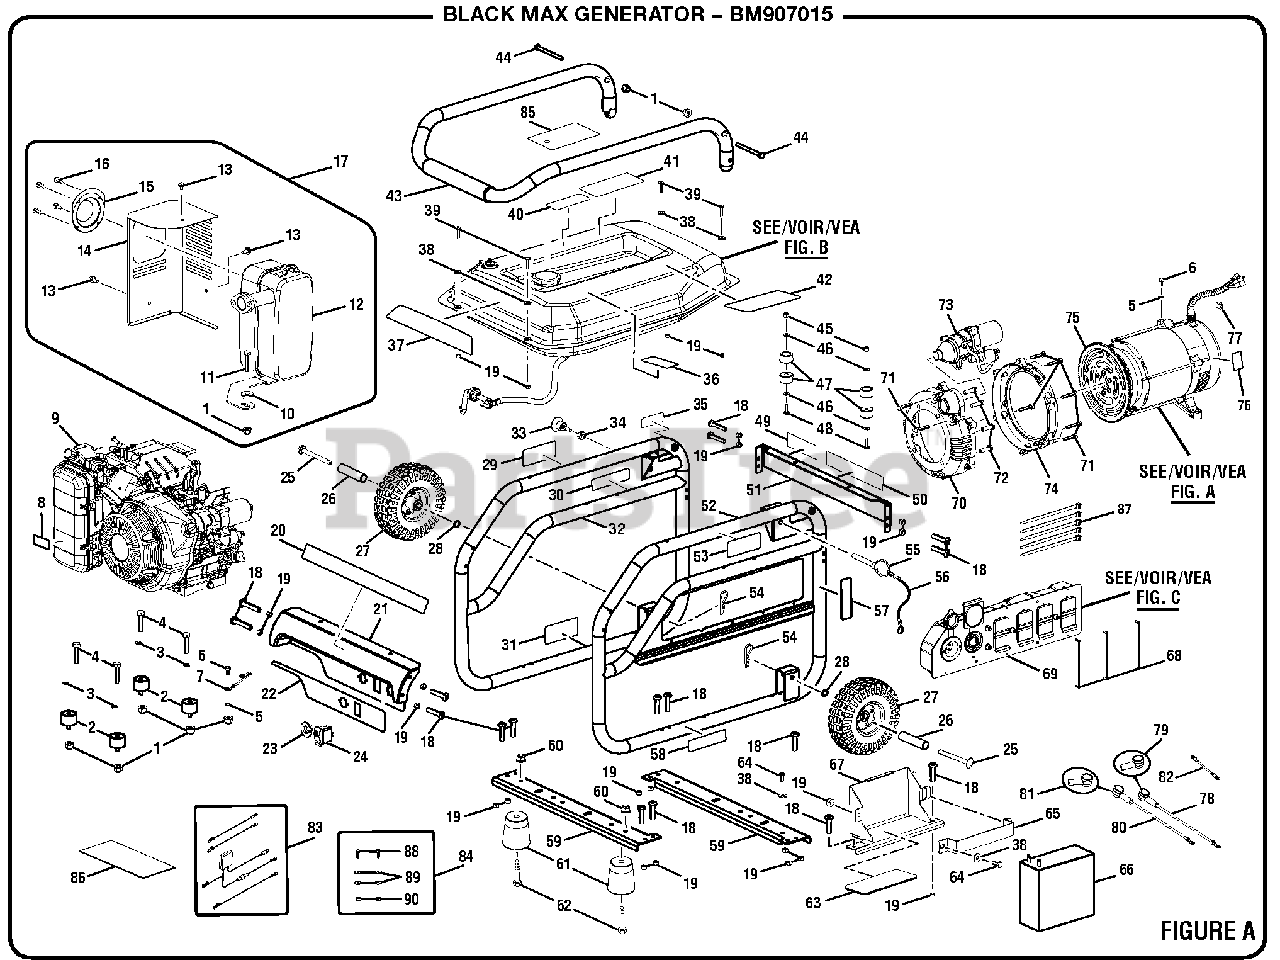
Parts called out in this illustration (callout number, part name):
1	Lock Nut (M8 x 1.25 in.)
3	Lock Washer (OD14.8 x ID8.5 x 1t)
4	Bolt (M8 x 35 mm, Hex Hd.)
5	Star Washer (M8)
6	Bolt (M8 x 15 mm, Hex Hd.)
7	Ground Wire Assembly
8	Electric Start Label
10	Washer (5/16 in.)
11	Bolt (5/16-24 x 5/8 in., Hex Hd.)
12	Muffler w/Brackets
13	Bolt (M6 x 9 mm, Hex Hd.)
14	Heat Shield
15	Spark Arrestor
16	Screw (8-32 x 3/8 in., Pan Hd.)
17	Muffler Assembly
18	Screw (M6 x 50 mm, T30 Torx Hd.)
19	Lock Nut (M6)
20	Logo Label (Honda)
21	Fuel Tank Support (Front)
22	Start Label
23	Fuel Valve Bezel
24	Engine Switch
25	Axle (M10 x 99 mm, Pan Hd.)
27	Wheel (10 in. x 3 in.)
28	Washer (OD19.75 x ID10.5 x 1t)
29	Fire Distance Label
30	Hot Surface Label
31	Combustion Label
32	Frame (Left)
33	Handle Release Pin
34	Hex Jam Nut (1/2-20)
35	Handle Release Label
36	E85 Label
37	Black Max Label
38	Washer (M6)
39	Bolt (M6 x 25 mm,T30 Torx Pan Hd.)
40	Fuel Stabilizer Label (Spanish)
41	CPSC Label
42	Danger Icon Label
43	Handle Assembly
44	Handle Pivot Bolt (M8 x 98 mm, Flat Hd.)
45	Lock Nut (M4)
46	Washer (OD9 x ID4.3 x 1t)
47	Rubber Bumper
48	Screw (M4 x 12 mm, Button Hd.)
49	Inquiries Label
50	Ground Warning Label
51	Fuel Tank Support (Back)
52	Frame (Right)
53	Fire Danger Label
54	Hitch Pin
55	Handle Lock Pin
57	Lock Pin Label
58	Lubricant Label
59	Frame Crossbar
60	Lock Nut (M8 x 1.25)
61	Rubber Foot
62	Bolt (M8 x 45 mm, Hex Hd.)
64	Bolt (M6 x 16 mm, Hex Hd.)
65	Battery Bracket
67	Battery Tray
68	Screw (6-20 x 3/8 in., Pan Hd.)
69	Control Panel Assembly See Figure C)
70	Front Housing
71	Bolt (M8 x 40 mm, Hex Hd.)
72	Bolt (3/8-16 x 1 in., Hex Hd.)
73	Electric Starter (12V)
74	Adaptor Housing
75	Generator Head (See Figure A)
76	Ground Label
77	Ground Lug
78	Battery Cable (Black)
79	Rubber Battery Cable Boot (Black)
80	Battery Cable (Red)
81	Rubber Battery Cable Boot (Red)
82	Bonding Wire
83	Wiring Harness
84	Fastener Kit
85	Warning Hangtag
86	Rubber Sheet
87	Zip Tie (5-1/2 in.)
88	Bolt (M5 x 10 mm, Hex Flange Hd.)
89	Washer (OD12 x ID5.2 x 0.5t)
90	Hex Nut (M5)
